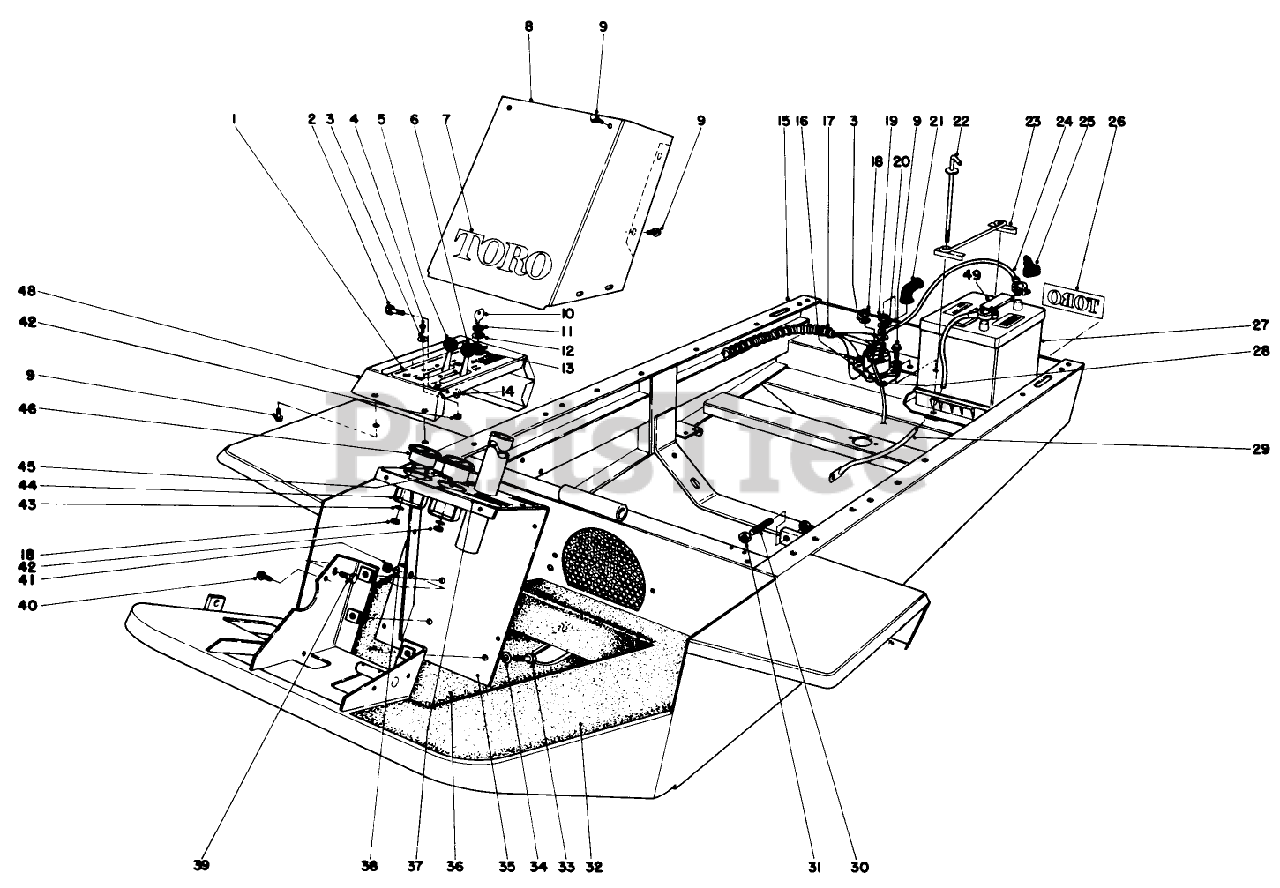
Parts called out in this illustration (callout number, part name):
2	SCREW-HH
3	WASHER-LOCK
4	10-24 X 5/8 PAN HD MS
9	SCREW-HWHTF
11	NUT-HH
12	WASHER-LOCK
13	SWITCH-STARTER
14	WASHER-FLAT
15	Frame
16	SOLENOID
18	NUT-HEX
19	NUT-JAM, BRASS
20	WASHER-LOCK
21	BATTERY BOOT
23	BATTERY HOLD DOWN WA
26	Muffler
29	BATTERY GROUND WIRE
31	NUT-JAM
32	NON SKID (TUNNEL)
33	SCREW-HH
34	WASHER-LOCK
36	NON-SKID-FLOOR
37	Decal-Instruction
38	WASHER-LOCK
39	SCREW-HH
40	SCREW-HWH
41	NUT-HEX
42	NUT-HEX
43	WASHER-LOCK, INT
44	CLAMP ASM
49	PUSH-ON BATTERY CAP
